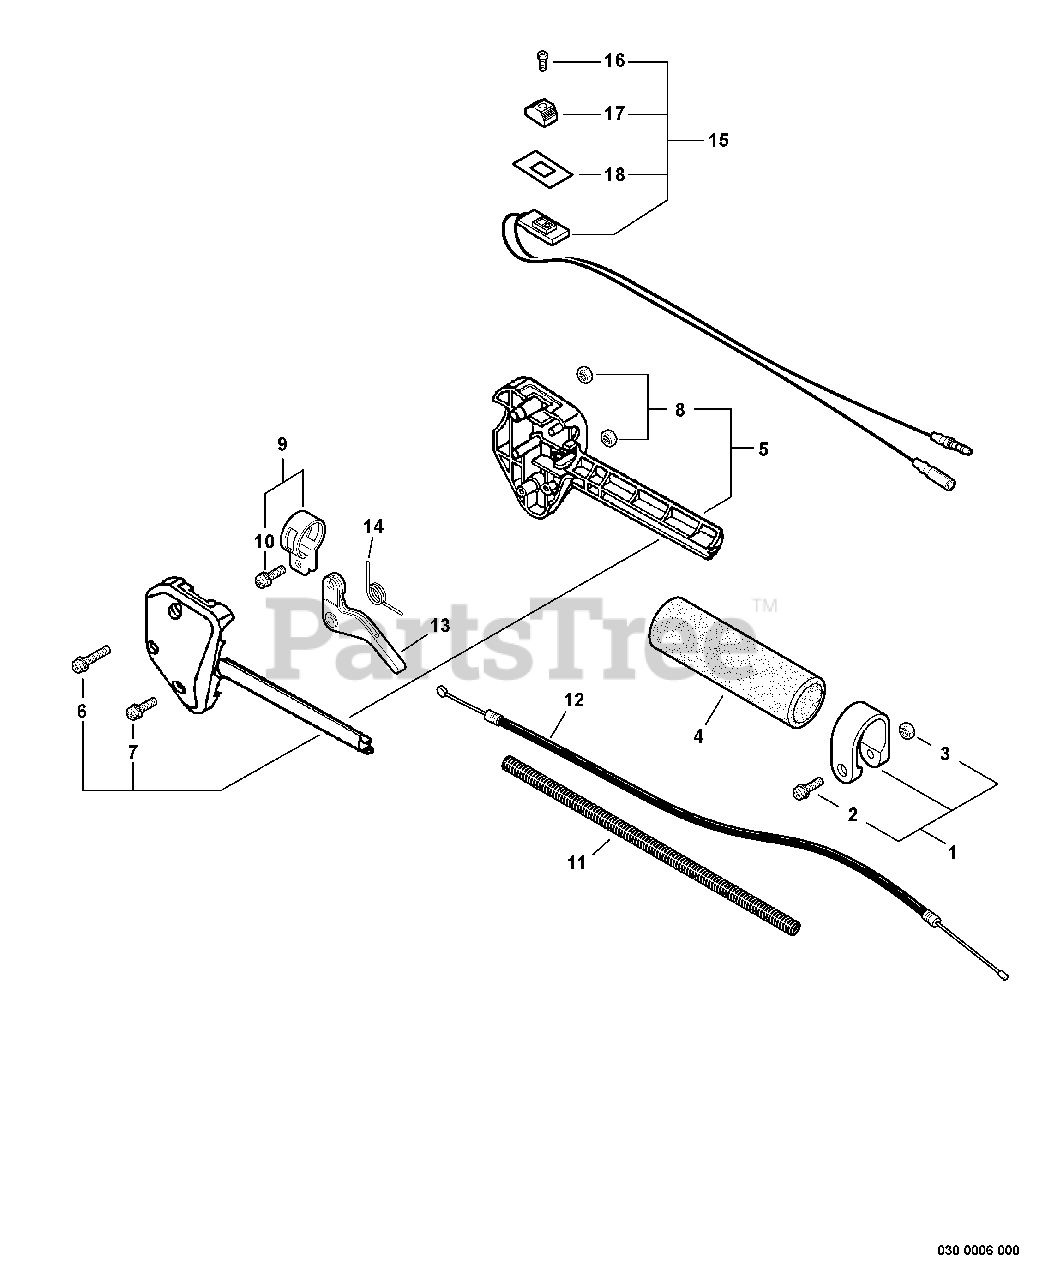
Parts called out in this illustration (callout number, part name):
1	CLAMP KIT
2	SCREW 5×28
3	NUT M5
4	GRIP, HANDLE
5	HANDLE KIT, CONTROL
6	SCREW 5×35
7	SCREW 5×25
8	NUT M5
9	CLAMP KIT
10	SCREW 5×14
11	TUBE, FLEXIBLE
12	CABLE, THROTTLE
13	TRIGGER, THROTTLE
14	SPRING, TORSION
15	SWITCH, ON-OFF
16	SCREW 3×10
17	KNOB, SWITCH - ORANGE
18	LABEL, SWITCH
